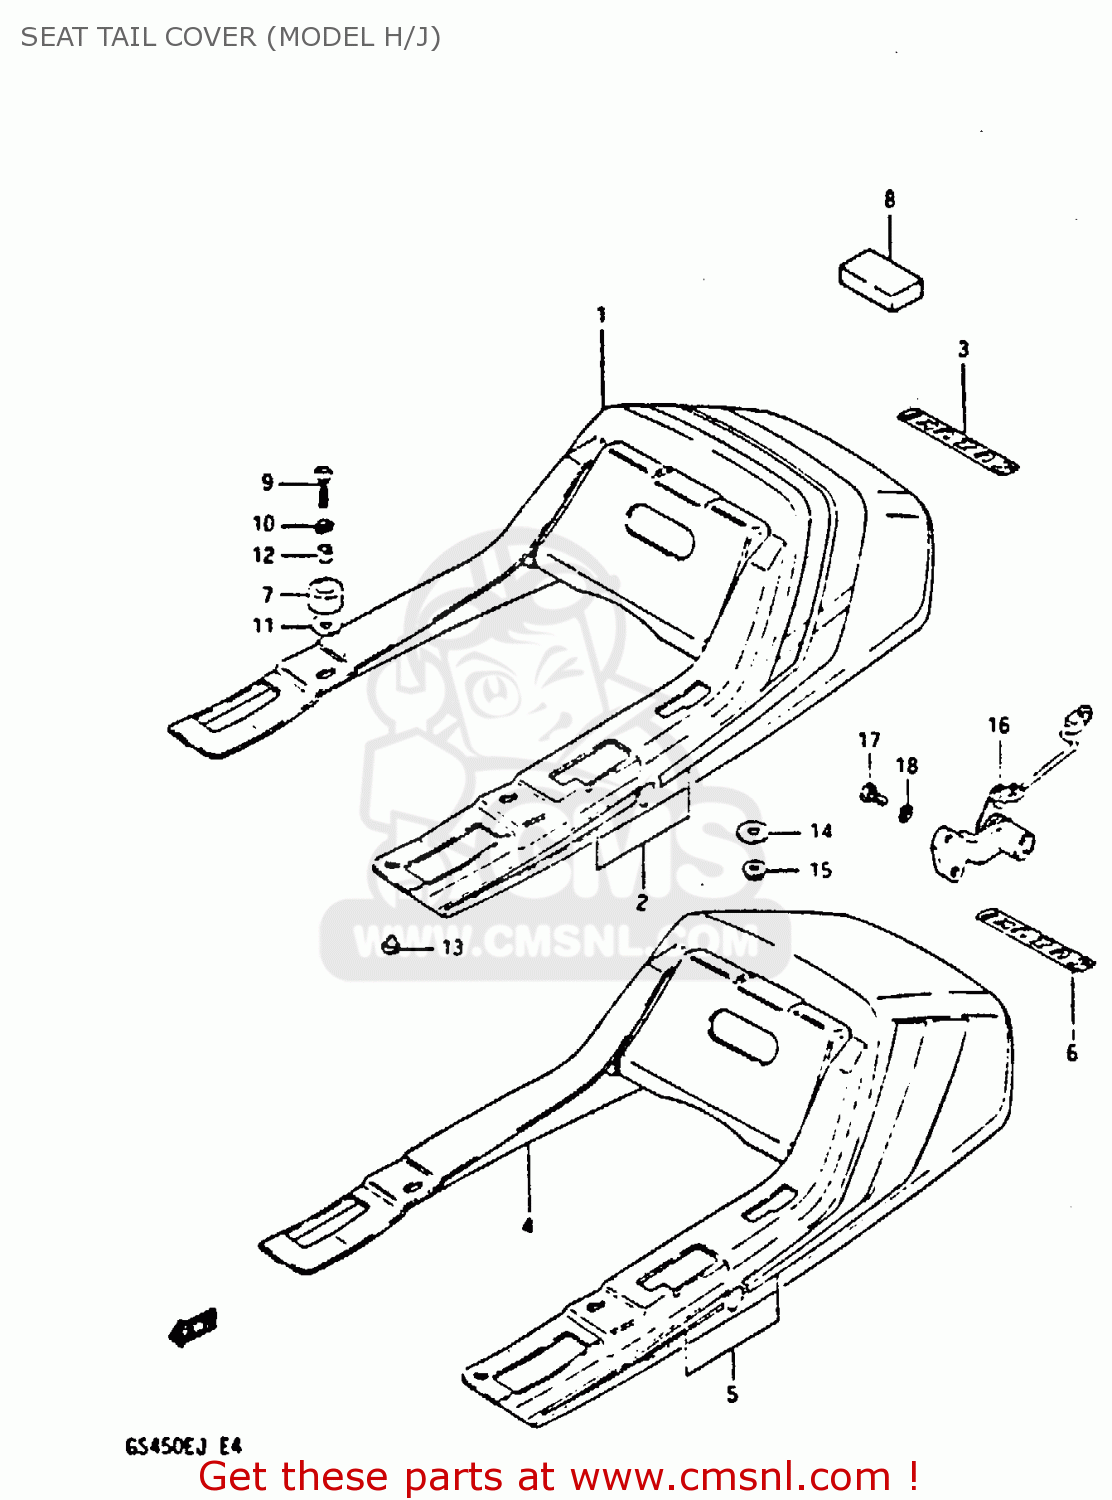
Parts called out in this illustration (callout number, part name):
1	TAIL COVER, SEAT (RED)
2	TAPE SET, SEAT TAIL COVER
3	EMBLEM(WHITE)
4	COVER,SEAT TAI
5	TAPE SET, SEAT TAIL COVER
6	EMBLEM
7	CUSHION,COVER
8	CUSHION
9	SCREW
10	WASHER,LOCK
11	WASHER (6.5X24X1.6)
12	SPACER
13	CUSHION
14	WASHER
15	NUT 6MM
16	LOCK ASSEMBLY,SEAT
17	BOLT 5X10
18	LOCK WASHER
